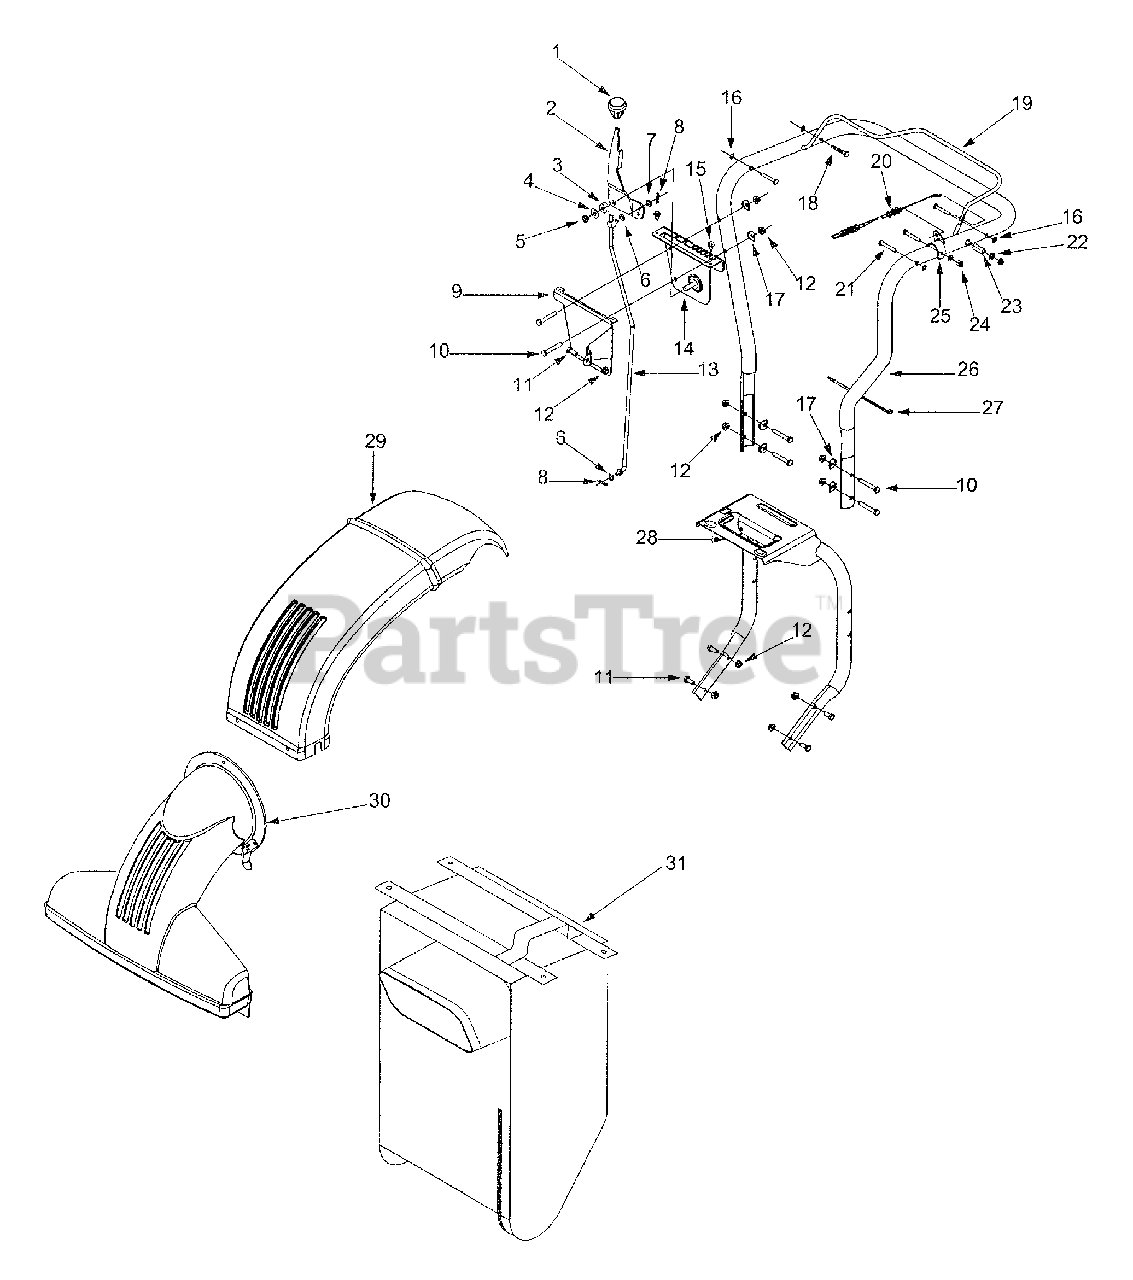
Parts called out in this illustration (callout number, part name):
1	Shift Knob
4	Flat Washer
5	Lock Nut 3/8-24
6	Spring Washer
7	Flat Washer .375 ID x .620 OD
8	Cotter Pin
11	Hex Cap Screw 5/16-18 x .75
12	Flange Lock Nut 5/16-18
13	Shift Rod
16	Push Nut .250
17	Shoulder Washer .320 ID x .93 OD
18	Pin .250 x 1.75
21	Hex Cap Screw 1/4-20 x 1.75
22	Flat Washer 5/16
23	Spacer .345 ID x .51 OD
24	Lock Nut 1/4-20
30	Nozzle Assembly
31	Vacuum Bag
